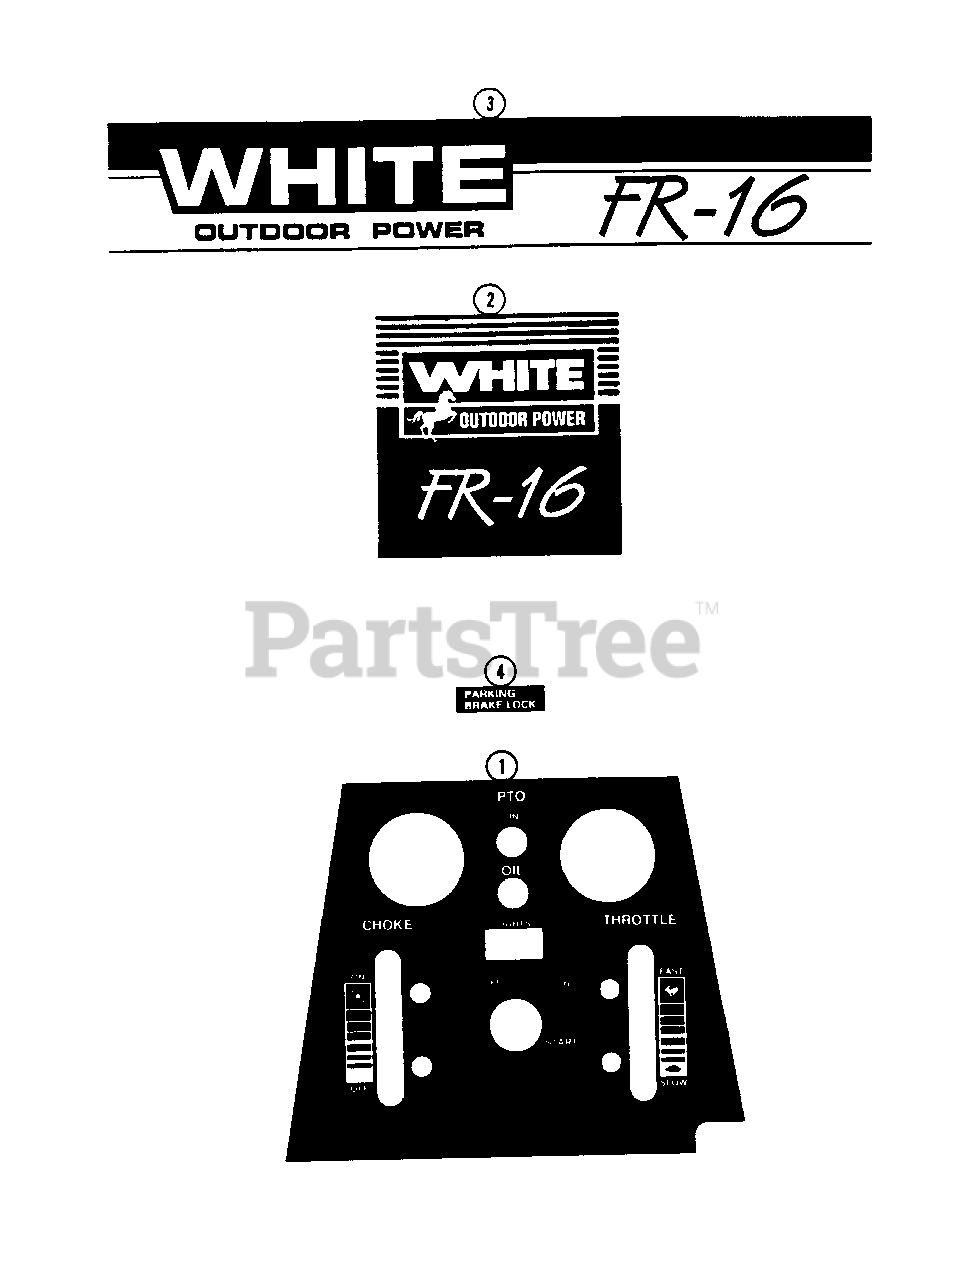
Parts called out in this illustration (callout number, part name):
2	DECAL - body front
3	DECAL - body side R.H.
3	DECAL - body side L.H.
4	DECAL - brake lock
